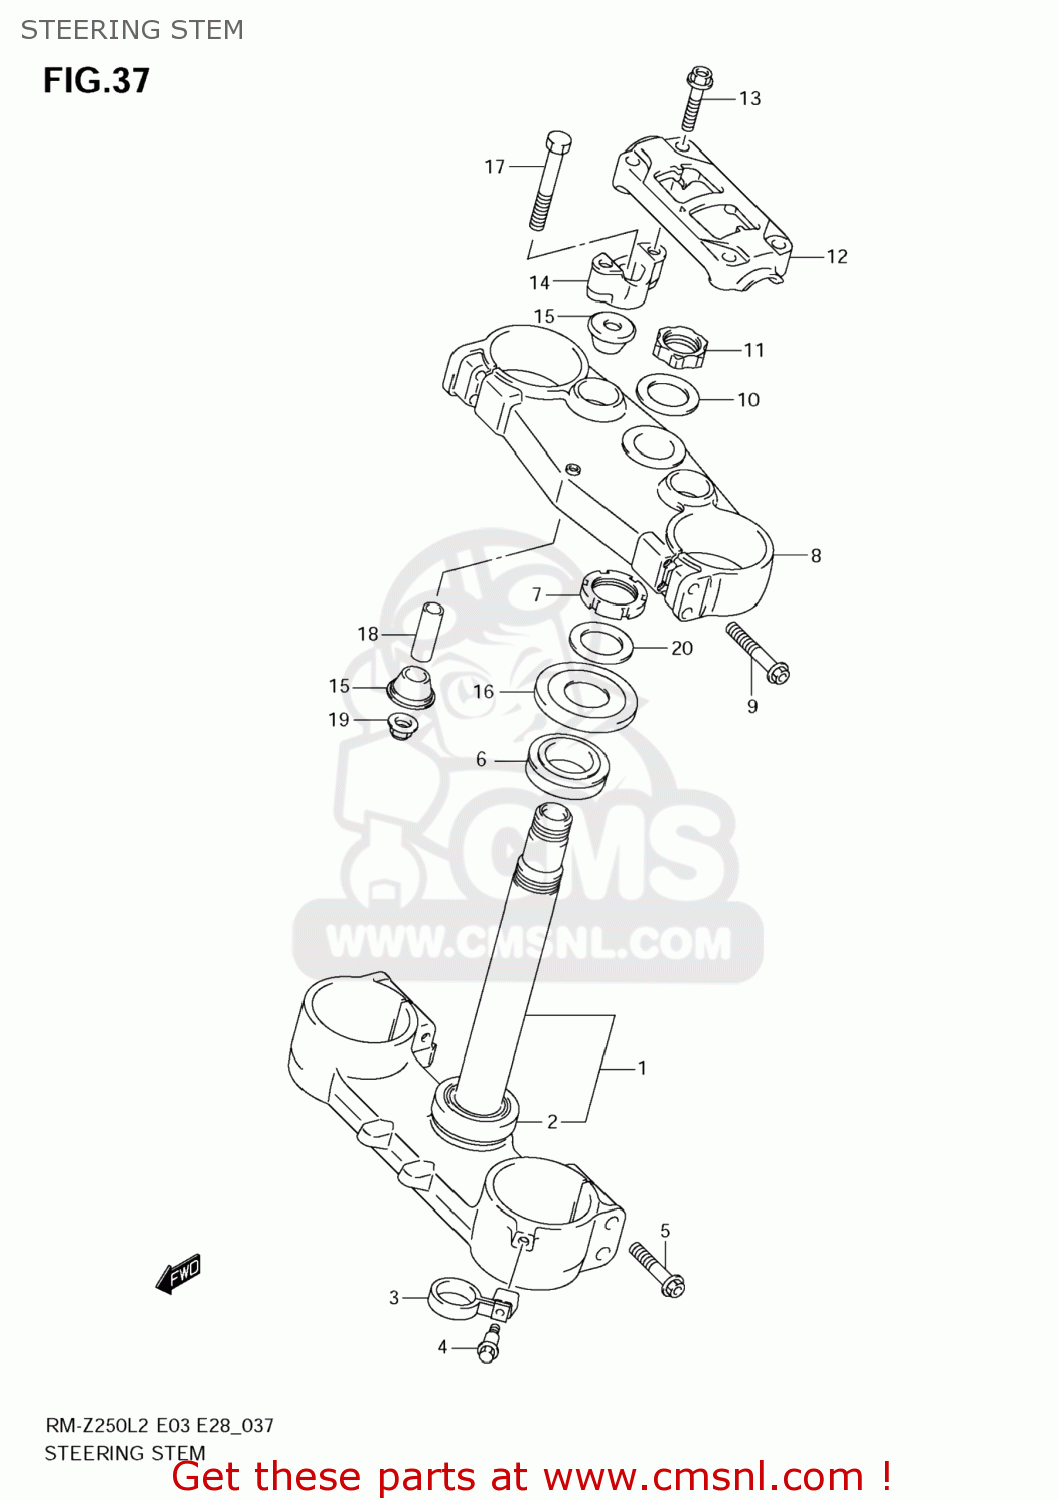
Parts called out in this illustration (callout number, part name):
1	STEM,STEERING
2	BEARING(30X52X16)
3	GUIDE,FR BRAKE HOSE
4	BOLT(6X20.5)
5	BOLT
6	BEARING(30X52X16)
7	NUT,STEERING
8	HEAD,STEERING STEM
9	BOLT
10	WASHER,STEM HEAD
11	NUT,STEM HEAD
12	HOLDER,HANDLE
13	BOLT
14	HOLDER,HANDLE
15	CUSHION,RUBBER
16	SEAL,STEERING UPR DUST
17	BOLT,HANDLE HOLDER
18	SPACER
19	NUT
20	WASHER,STEERING NUT
